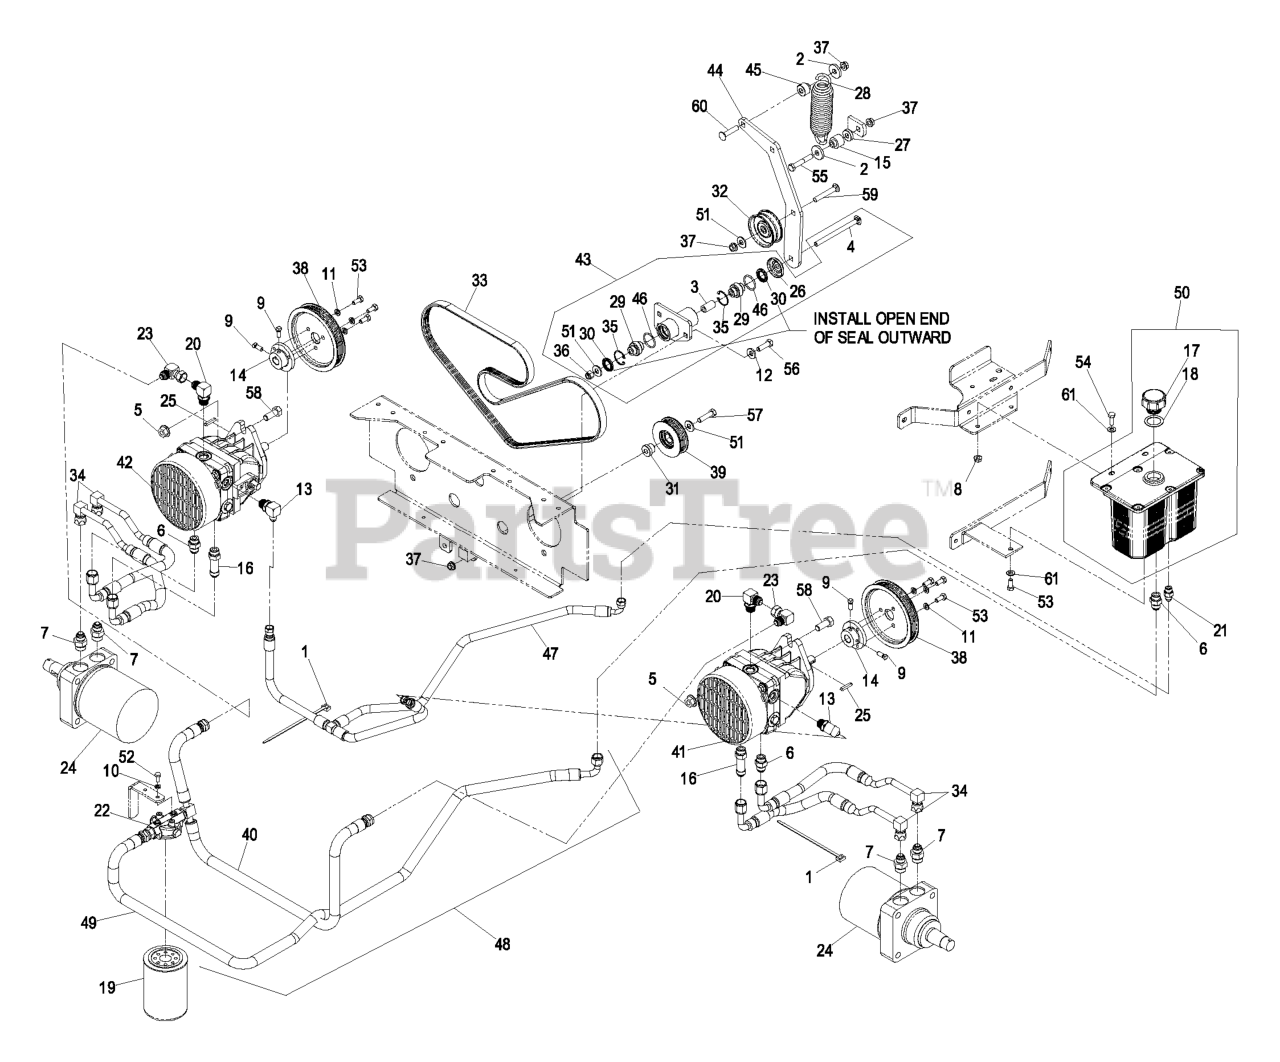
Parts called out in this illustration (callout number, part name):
1	TIE-PLASTIC
4	BOLT CARR 3/8-16X5
5	NUT-HHF
6	FITTING-STRAIGHT
7	FITTING-STRAIGHT
9	SCREW-SET
10	WASHER-LOCK
11	WASHER-LOCK
12	WASHER-BELLEVILLE
13	FITTING-ELBOW, 90 DEG
14	HUB-PUMP
15	SPACER-SPRING, FAN PUMP
16	ADAPTER-STR, LONG
17	Cap-Reservoir, HYD
18	GASKET-CAP
19	FILTER,XP HYD 25 MICRON
20	FITTING-90 DEG
21	FITTING-STRAIGHT
22	HEAD-FILTER
23	FITTING-90 DEG
26	GUARD-TOP
27	SPACER-BRACKET, GUIDE
29	BEARING-SPHERICAL
30	SEAL-LIP, SINGLE
31	SPACER,LOWER FRAME IDLER
32	IDLER,PUMP
33	BELT,PVK 5 X 70.5
34	HYD HOSE ASM
35	RING-SNAP
36	NUT-LOCK, NI
37	NUT-HHF, WHIZ
38	SHEAVE,5K 5.6" PD POLY-V
39	ASM,LOWER FRAME IDLER
40	HOSE,31 EPS PUMP INLET
43	KIT,PUMP IDLER
44	ARM,PUMP IDLER
47	ASM,CASE DRAIN HOSE
50	HYDRAULIC TANK ASM
51	WASHER-FLAT
52	SCREW-HH
53	SCREW-HH
54	SCREW-HH
55	SCREW-HH
56	SCREW-HH
57	SCREW-HH
58	SCREW-HH
59	Bolt-Carriage 3/8-16 X 2 1/4
60	SCREW-CARR
61	WASHER-PLAIN
